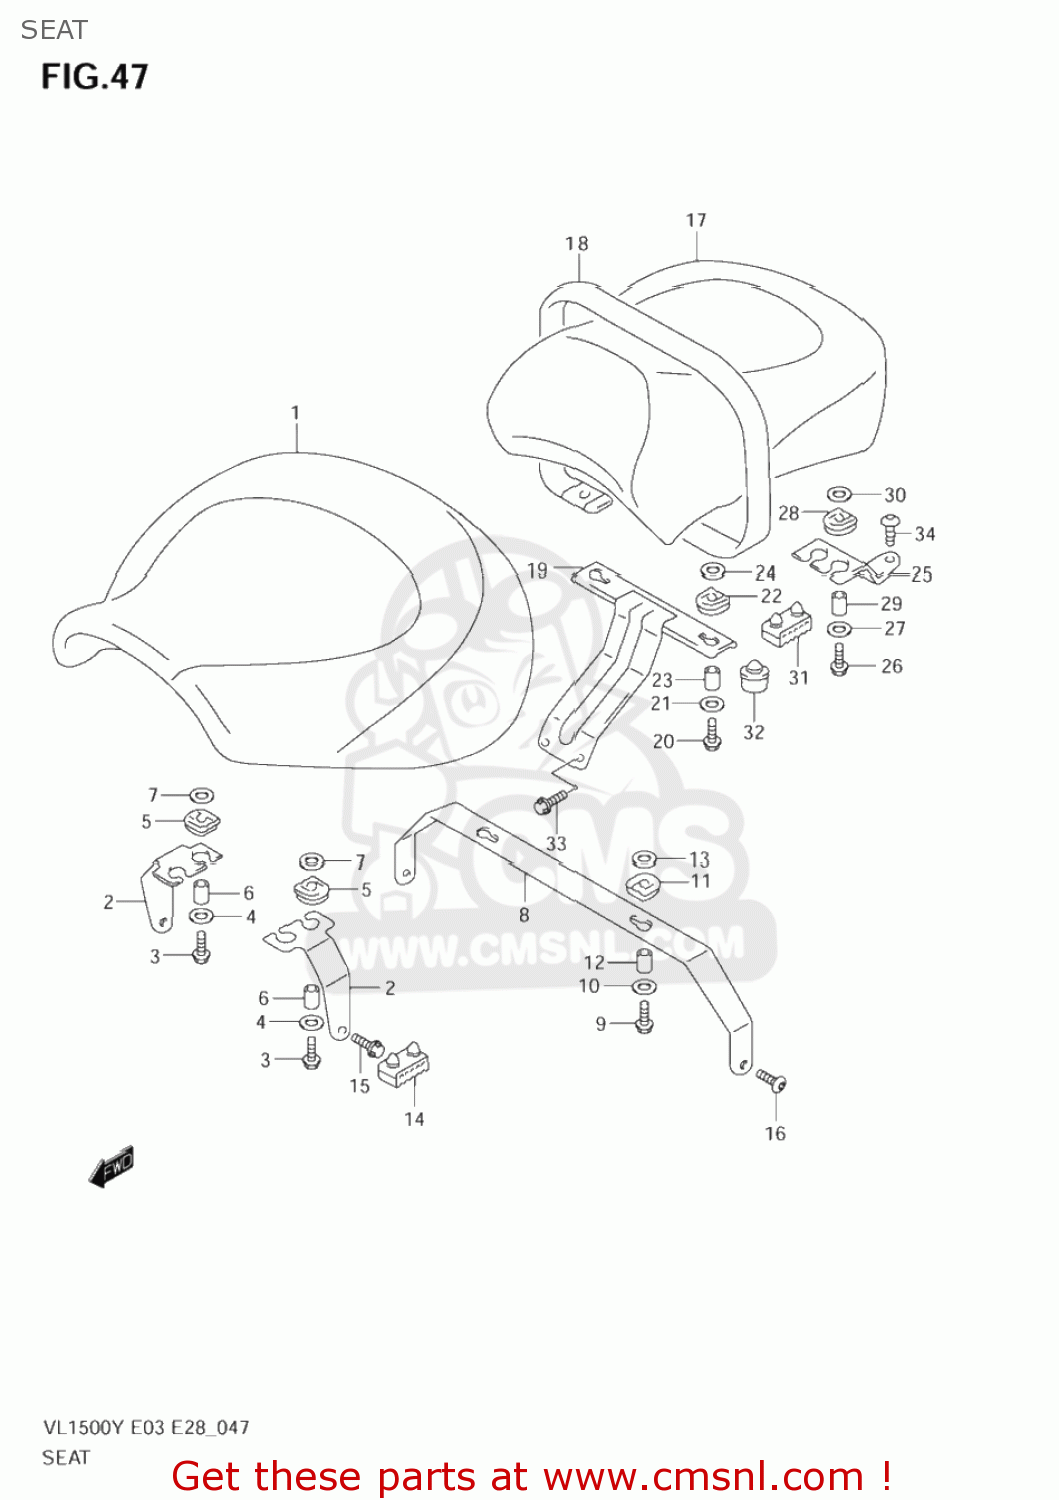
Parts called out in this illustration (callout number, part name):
1	SEAT ASSY
2	BRACKET,SEAT FR
3	BOLT
4	WASHER(6.5X20X1.6)
5	CUSHION
6	SPACER
7	WASHER(6.5X20X1.6)
8	BRACKET,SEAT RR
9	BOLT
10	WASHER(6.5X20X1.6)
11	CUSHION
12	SPACER
13	WASHER(6.5X20X1.6)
14	CUSHION,SEAT(40X20X15)
15	BOLT
16	BOLT(8X16)
17	SEAT ASSY,PILLION
18	BAND ASSY,PILLION SEAT(BLACK)
19	BRACKET,SEAT FR
20	BOLT
21	WASHER(6.5X20X1.6)
22	CUSHION
23	SPACER
24	WASHER(6.5X20X1.6)
25	BRACKET,SEAT RR
26	BOLT
27	WASHER(6.5X20X1.6)
28	CUSHION
29	SPACER
30	WASHER(6.5X20X1.6)
31	CUSHION,SEAT(40X20X15)
32	CUSHION
33	BOLT
34	BOLT(8X16)
